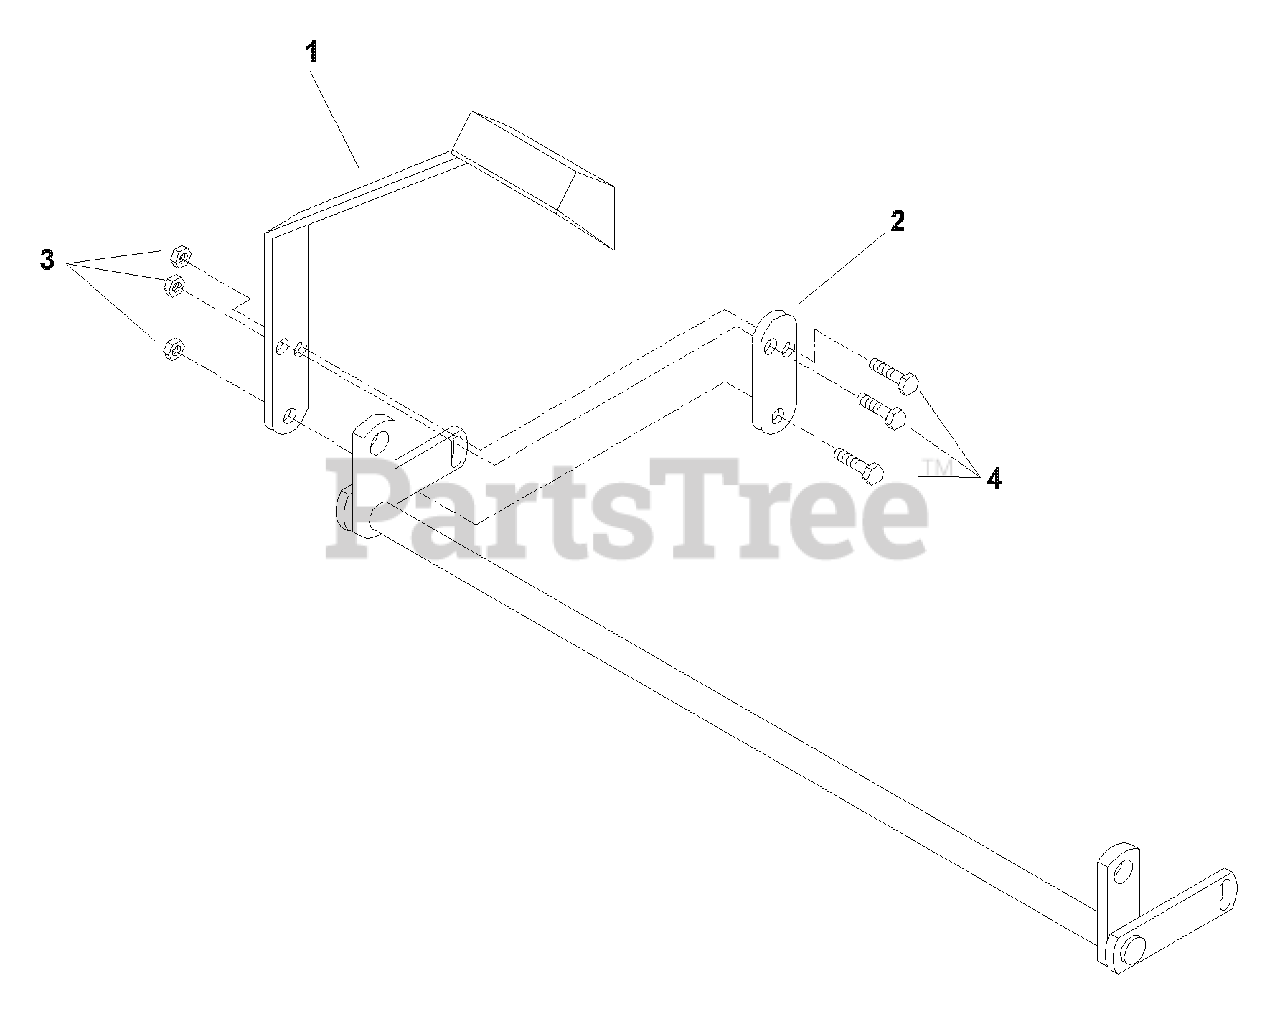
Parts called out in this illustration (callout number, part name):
1	Lift Pedal W/pad
2	Tightening Plate
3	Nut 3/8C Nyloc
4	HCS 3/8C X 1 1/2
